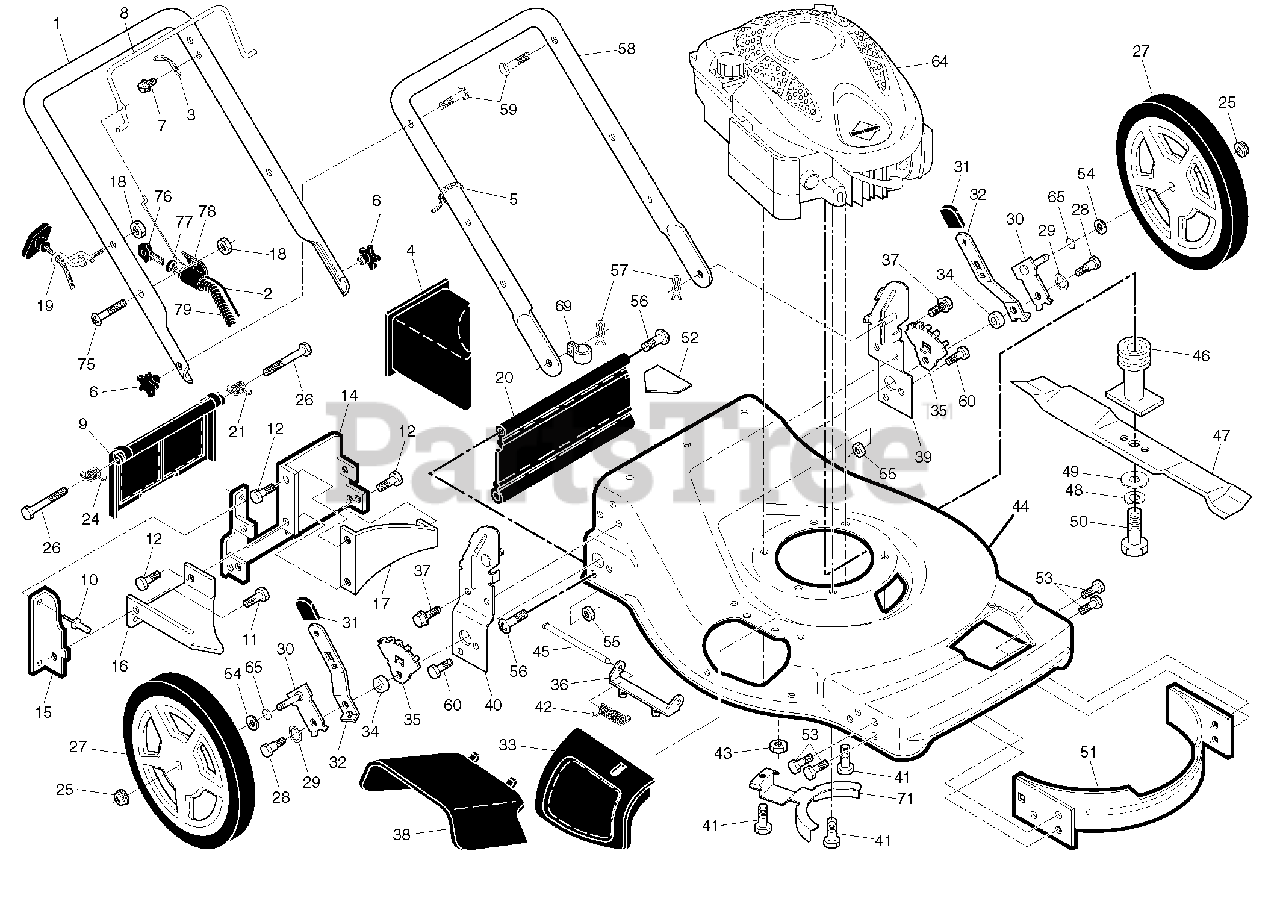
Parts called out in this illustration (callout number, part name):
1	Upper Handle
2	Cable, Operator Presence
3	Bracket, Upstop
4	Mulcher Plug
5	Wire Tie
6	Handle Knob
7	Screw
8	Control Bar
9	Rear Door Assembly
10	Pop Rivet
11	Screw, Self-Tapping #10-24 x 5/8
12	Screw, Hex Hex Head, Sems 1/4-20 x 1/2
14	Back Plate
15	Side Baffle
16	Discharge Baffle
17	Rear Baffle
18	Keps Locknut 1/4-20
19	Rope Guide
20	Rear Skirt
21	Spring, Rear Door, LH
24	Spring, Rear Door, RH
25	Nut, Hex, Flanged
26	Bolt, Rear Door
27	Wheel & Tire Assembly, Rear
28	Bolt, Shoulder 3/8-16 x 1
29	Washer, Curved, Cylindrical
30	Axle Arm Assembly
31	Selector Knob
32	Selector Spring
34	Spacer
35	Wheel Adjusting Bracket
36	Hinge Bracket Assembly
37	Screw, Sems, Thread Cutting 5/16-18 x 3/4
38	Discharge Deflector
39	Handle Bracket Assembly, LH
40	Handle Bracket Assembly, RH
41	Screw, Hex Head, Threaded, Rolled 3/8-16 x 1-1/8
42	Spring, Torsion
43	Nut, Hex, Nylock
44	Kit, Mower Housing
45	Rod, Hinge
46	Blade Adapter / Pulley
47	Blade, 22"
48	Washer, Hardened
49	Washer, Helical
50	Screw, Machine, Hex Head 3/8-24 x 1-3/8 Grade 8
51	Kit, Front Baffle
52	Danger Decal
53	Screw, Serrated, TT 1/4-20
54	Washer, Flat
55	Nut, Hex 3/8-16
56	Hinge Screw 1/4-20 x 1-1/4
57	Hairpin Cotter
58	Lower Handle
59	Handle Bolt
60	Bolt, Hex Head 3/8-16 x 3/4
61	Nut, Hex 3/8-16
65	O-Ring
69	Clip, Cable
71	Belt Keeper
75	Screw
76	Key
77	Nut, Cap
78	Key Start Switch
79	Wiring Harness
79	Operator's Manual, English
79	Operator's Manual, French
79	Repair Parts Manual
